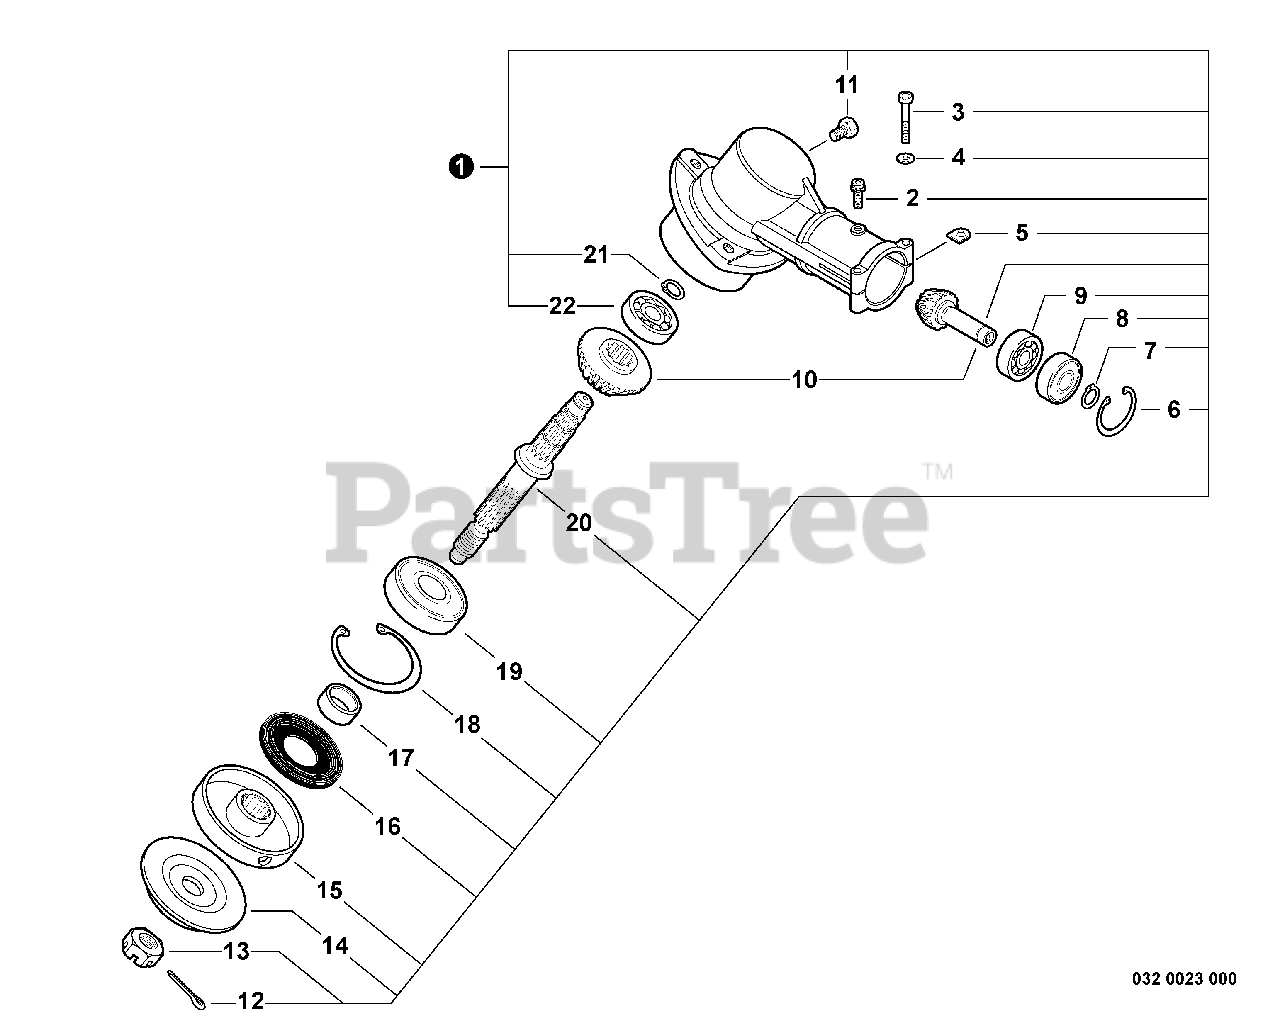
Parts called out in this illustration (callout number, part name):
1	GEAR CASE ASSY
2	SCREW 5×10
3	BOLT 5×35 SP
4	WASHER, FLAT 5.5×10×0.8
6	RING, SNAP Ø22
7	RING, SNAP Ø10
8	BEARING, BALL 6900Z
9	BEARING, BALL 6900
10	GEAR SET
11	BOLT M8×8
12	PIN, COTTER 2×22
14	PLATE, ADAPTOR - LOWER
15	PLATE, ADAPTOR - UPPER
16	SEAL, OIL 22
17	SPACER 11.8×15×9
18	RING, SNAP Ø32
19	BEARING, BALL 6201
20	SHAFT, GEAR
21	RING, SNAP Ø12
22	BEARING, BALL 609
